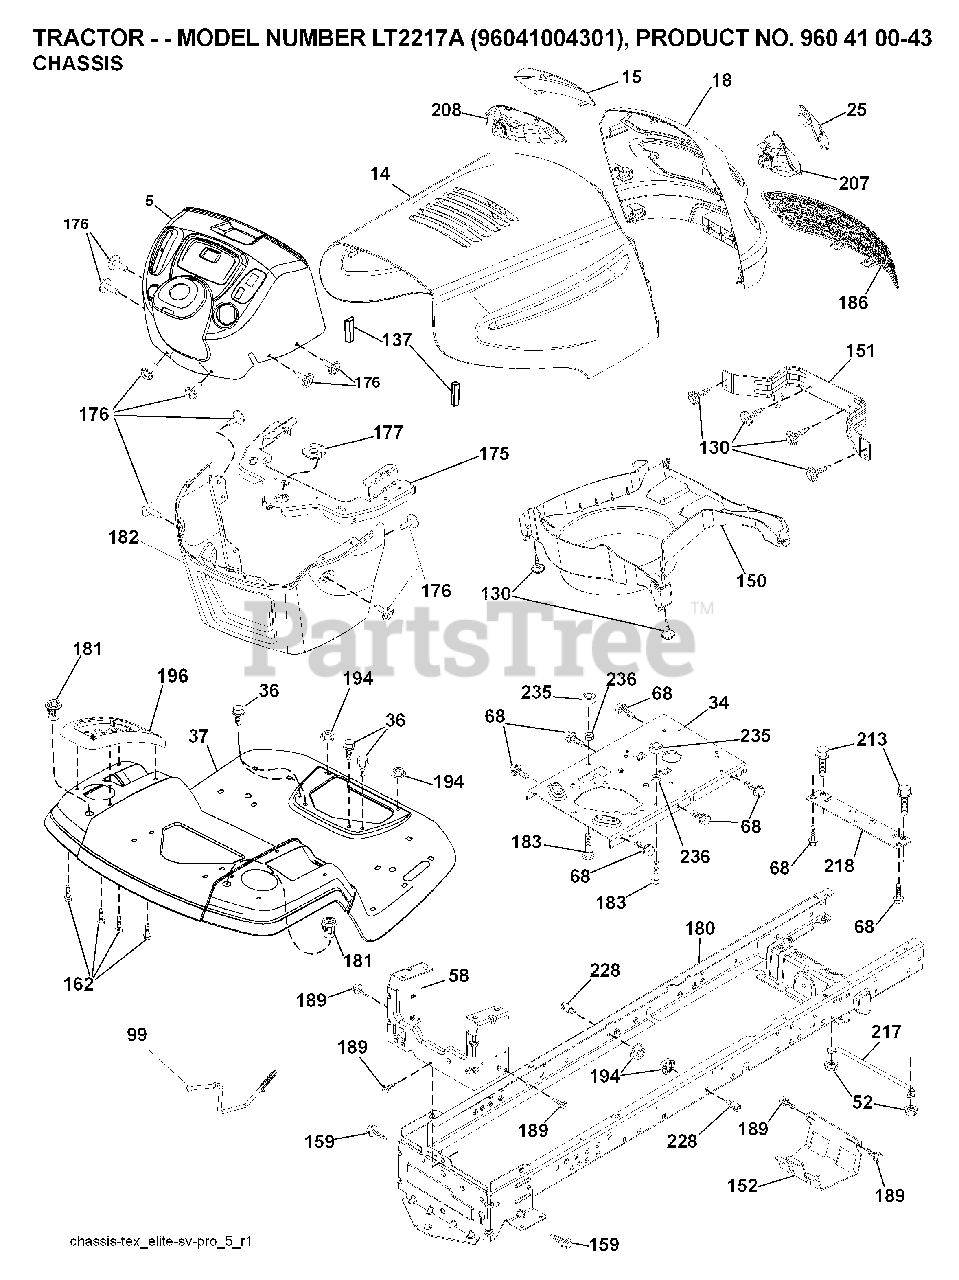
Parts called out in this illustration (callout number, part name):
34	PLATE.ENGINE.WELDED.CHASSIS
36	SCREW 5/16"
52	LOCKNUT
58	DRAWBAR UPPER 2PC SMALL FENDER
99	ROD ASM BYPASS
130	SCREW
137	BUMPER.HOOD.LARGE.1.75"
151	BRACKET PIVOT
152	SHIELD BROWNING
159	SCREW, 3/8-16X3/4
162	SCREW.1/4-20X5/8
175	CROSSMEMBER.LT
176	SCREW.#10-24X5/8.RN.QU
177	BUSHING STEERING
180	CHASS.WLDMNT.TL.12GA/2P.48/54
181	FEND/FTRST.PCH.CPH.NFW
182	DASH.LOWER.LT.CCS
183	BOLT.5/16-18X1-1/4 FULL.THREAD
189	SCREW
194	NUT LOCK HEX FLANGE 5/16-18
196	CONSOLE.ASM.DECK.LIFT.TLT.BLAC
207	BEZEL GRILL RH
208	BEZEL GRILL LH
213	BOLT
217	ROD.PIVOT.HOOD
218	X-PIECE.HOOD.STOP.NON/
228	STUD.FASTNER.W/ANTI-ROTATE
235	SPACER FENDER
236	NUT.CENTERLOCK.5/16-
